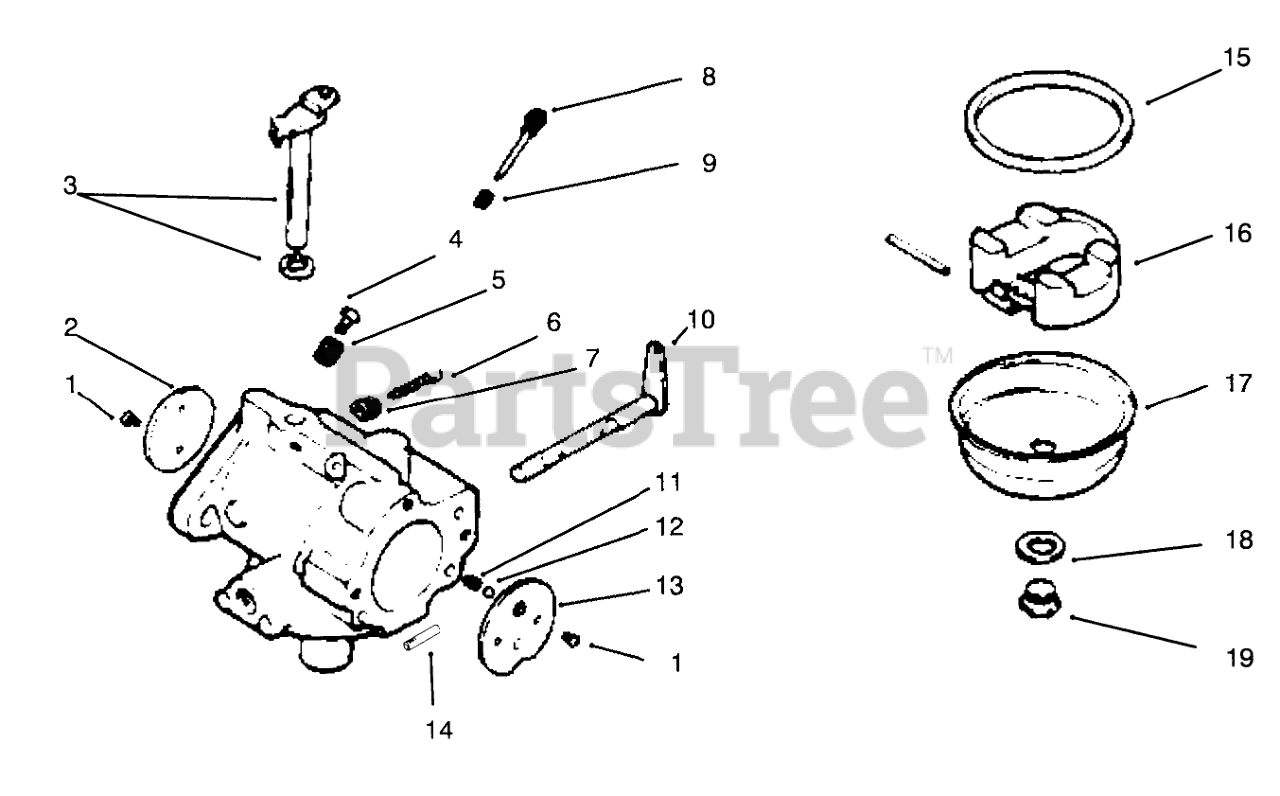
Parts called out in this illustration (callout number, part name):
1	Screw
2	Plate-Throttle
3	Shaft-Throttle
4	Needle-Idle Fuel Adj.
5	Screw-Bowl
6	Screw-Idle Speed Adj.
7	Spring-Idle Speed
8	Needle-Main Fuel
9	Screw-Bowl
10	Lever-Choke
11	Spring-Choke Friction
12	Ball-Choke Friction
13	Plate-Choke
14	Jet-Main
15	Gasket
16	Kit-Float (Incl. Pin)
17	Bowl-Fuel
18	Gasket-Retainer Screw
19	Screw-Bowl Retainer
